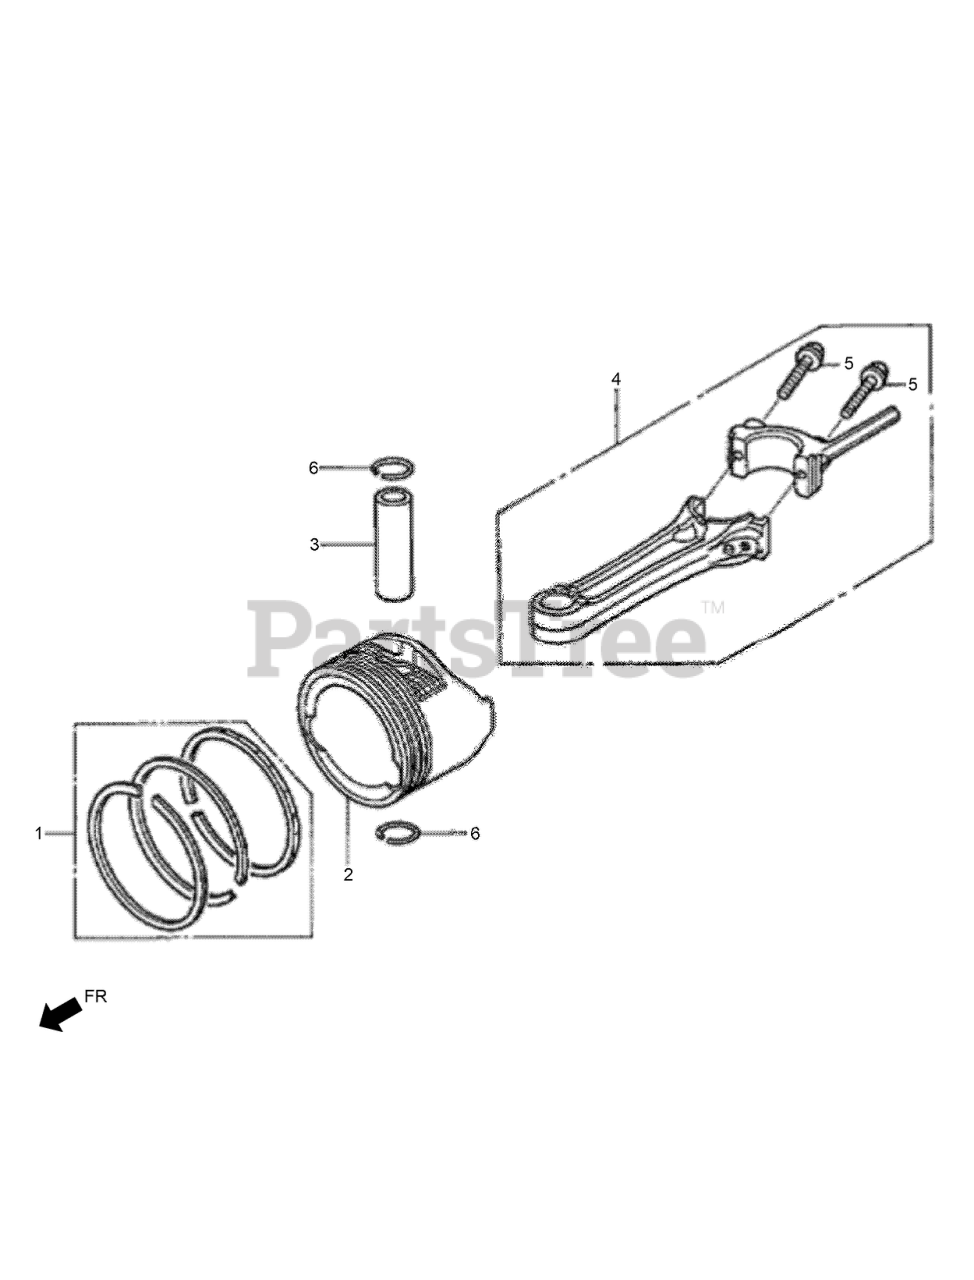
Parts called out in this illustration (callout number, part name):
1	RING SET-PISTON (from S/N 2277163 to 2531728)
1	RING SET-PISTON (STD) (from S/N 2277163 to 2531728)
1	RING SET-PISTON (STD) (from S/N 2531729)
1	RING SET-PISTON (to S/N 2277162)
1	RING SET-PISTON (to S/N 2531728)
2	PISTON (to S/N 2277162)
2	PISTON (from S/N 2531729)
2	PISTON (from S/N 2277163 to 2531728)
3	PIN-PISTON (from S/N 4433466)
3	PIN-PISTON (to S/N 4433465)
4	ROD ASM-CONNECTING
5	BOLT-CONNECTING ROD
6	CLIP-PISTON PIN-13MM
